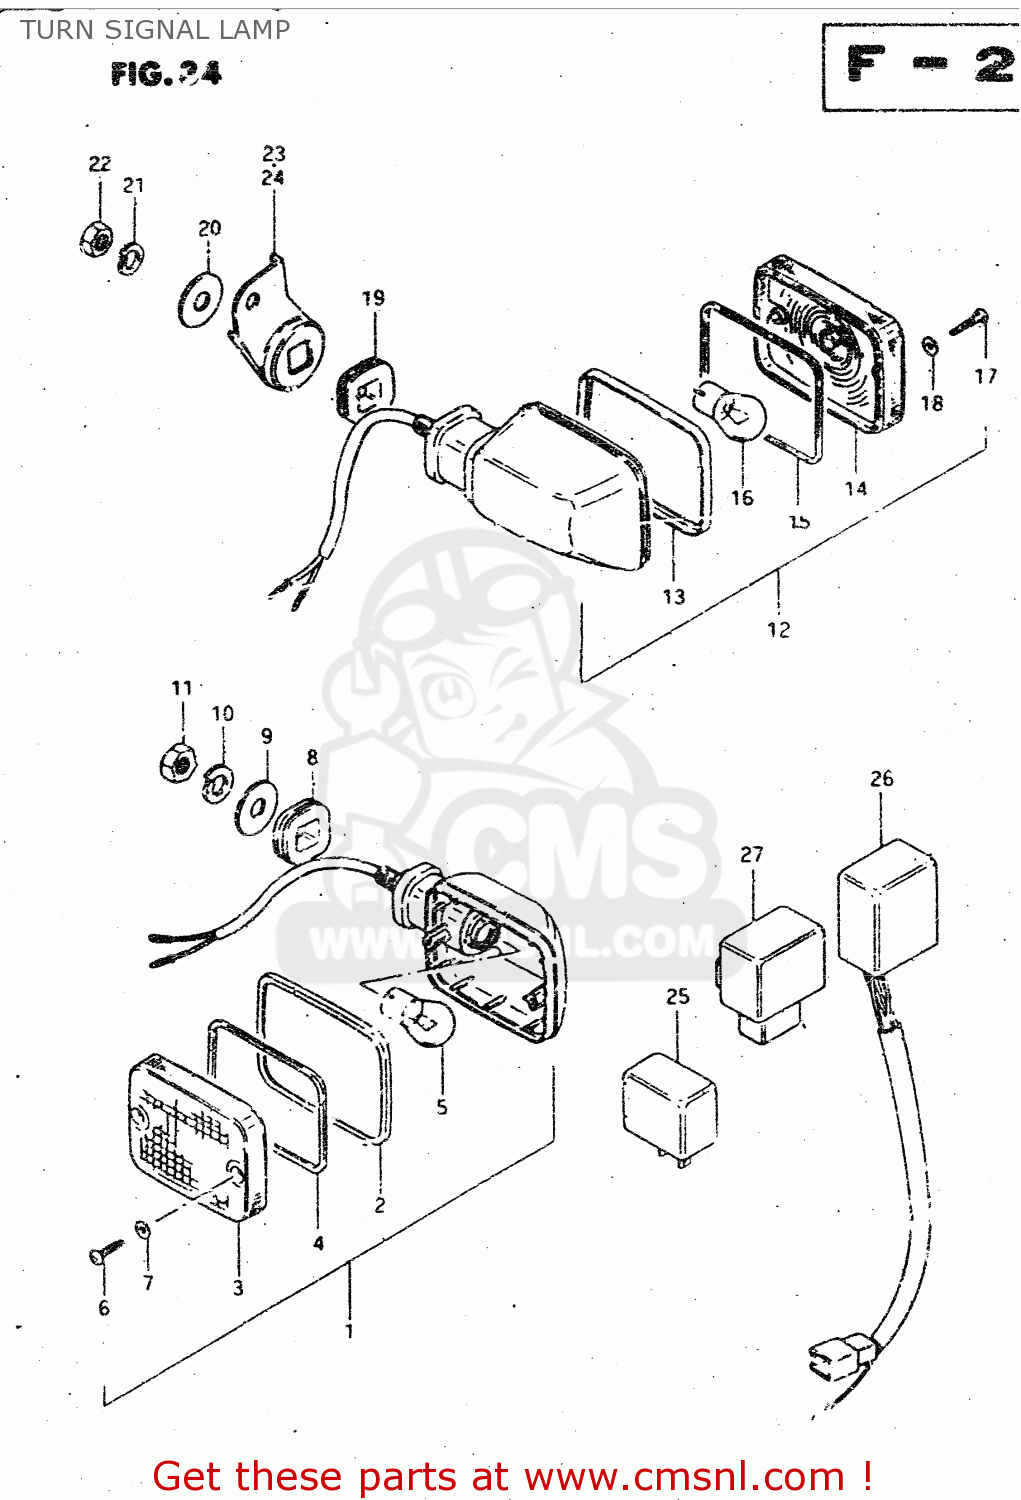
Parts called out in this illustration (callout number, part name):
1	LAMP ASSEMBLY,FRONT TURN SIGNAL
2	RIM
3	LENS
4	GASKET (NAS)
5	BULB(12V23W,STANLEY,A4577A)
6	SCREW
7	GASKET (NAS)
8	CUSHION
9	WASHER (10.5X30X2.3)
10	LOCK WASHER
11	NUT
12	LAMP ASSEMBLY,FRONT TURN SIGNAL
13	RIM
14	LENS
15	GASKET (NAS)
16	BULB(12V23W,STANLEY,A4577A)
17	SCREW
18	GASKET (NAS)
19	CUSHION
20	WASHER (10.5X30X2.3)
21	LOCK WASHER
22	NUT
23	BRACKET,RR TURNSIGNAL LAMP,R
24	BRACKET,RR TURNSIGNAL LAMP,L
25	RELAY ASSY,TURNSIGNAL
26	UNIT,TURN SIGNAL CONTROL
27	UNIT,TURN SIGNAL CONTROL
